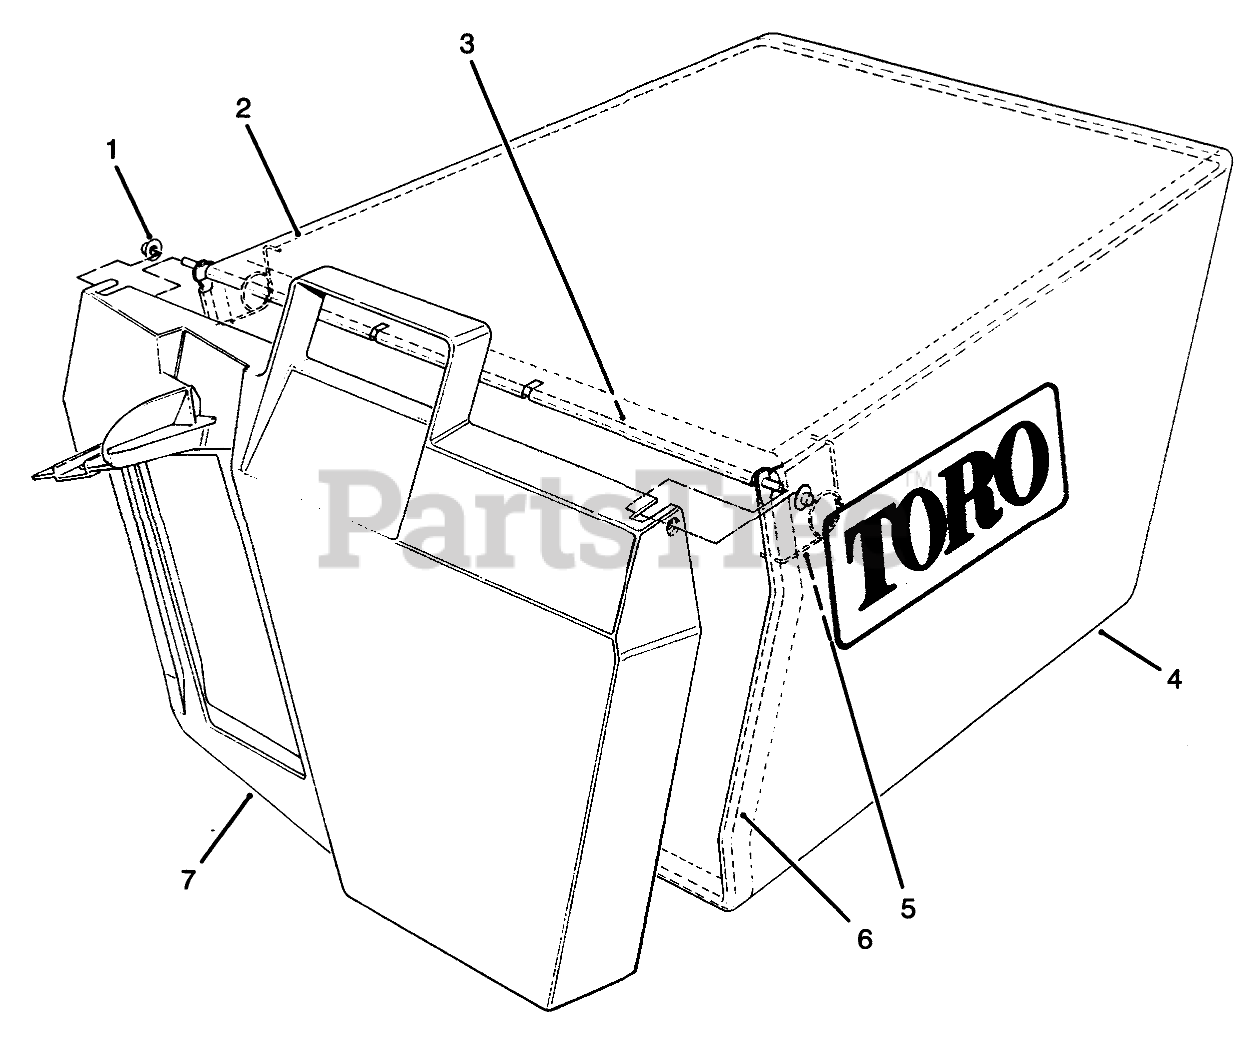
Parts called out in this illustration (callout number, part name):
1	NUT-PUSH
2	FRAME-BAG, UPPER
3	HINGE-DOOR, BAG
4	Bag
5	SPRING
6	BAG FRAME
7	BAG DOOR
